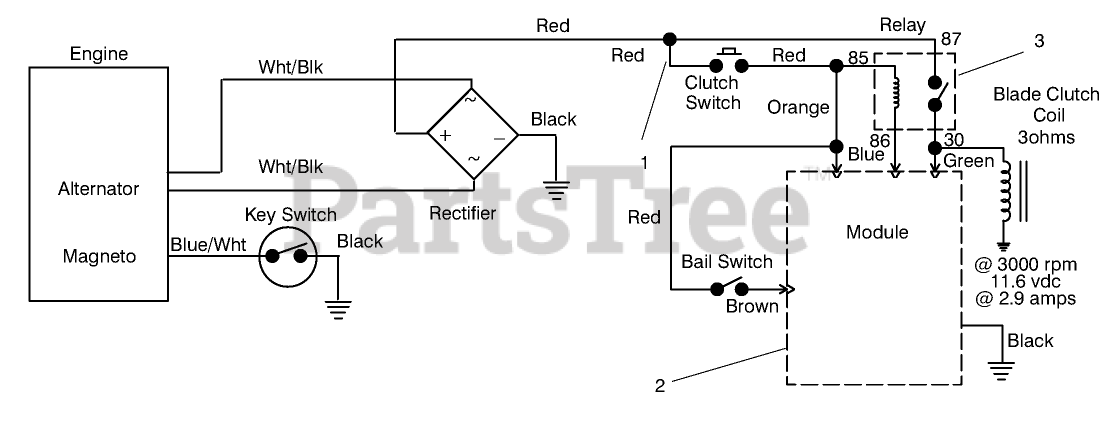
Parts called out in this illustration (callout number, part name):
1	WIRE HARNES - KAWASAKI
2	MODULE
3	RELAY
